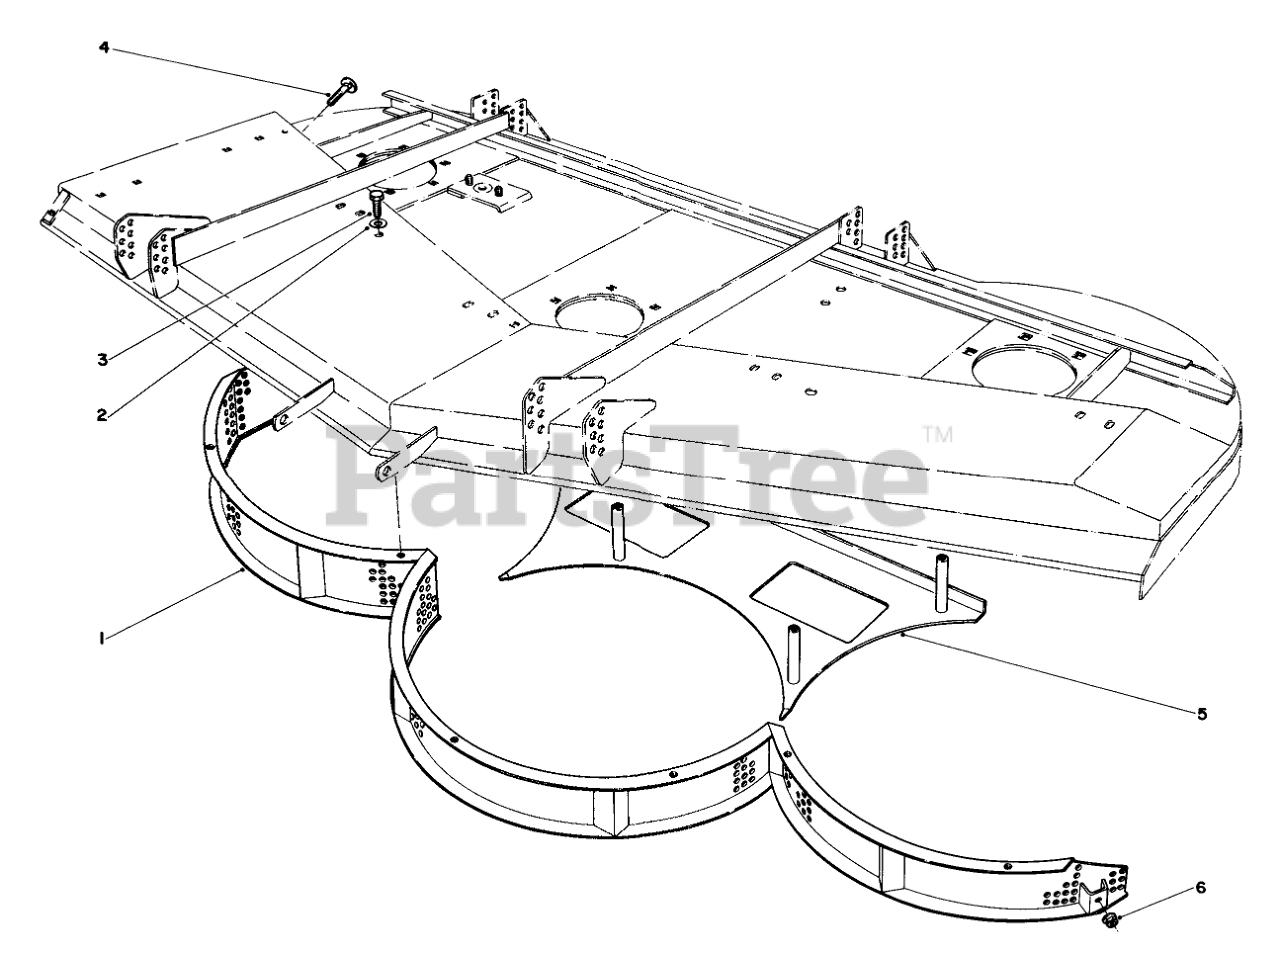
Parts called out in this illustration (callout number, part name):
1	Mulcher Screen
2	WASHER-LOCK
3	SCREW-HH
4	BOLT-CARR
5	Shelf-Bottom Rear
6	NUT-HHF, WHIZ
